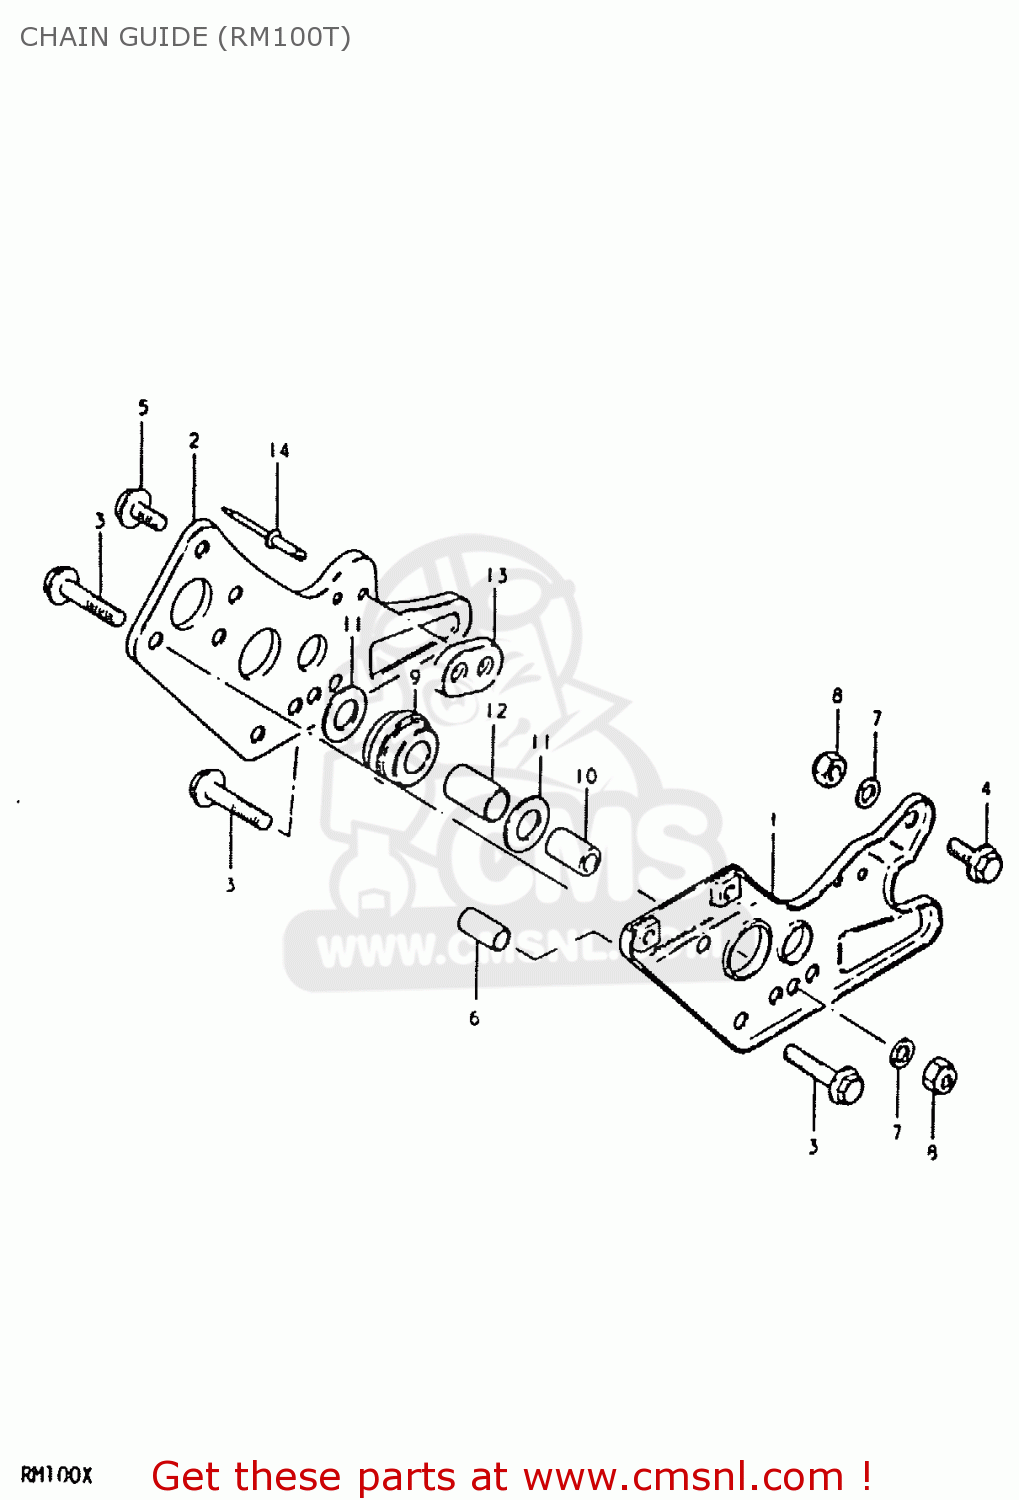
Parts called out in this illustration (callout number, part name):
1	PLATE,CHAIN GUIDE,OUTER
2	PLATE,CHAIN GUIDE,INNER
3	BOLT 6X35
4	BOLT
5	BOLT
6	SPACER(6.8X10X24.2)
7	WASHER
8	NUT 6MM
9	ROLLER,CHAIN GUIDE
10	SPACER,CHAIN GUIDE ROLLER
11	WASHER
12	BUSHING
13	PAD,DRIVE CHAIN GUIDE
14	RIVET
